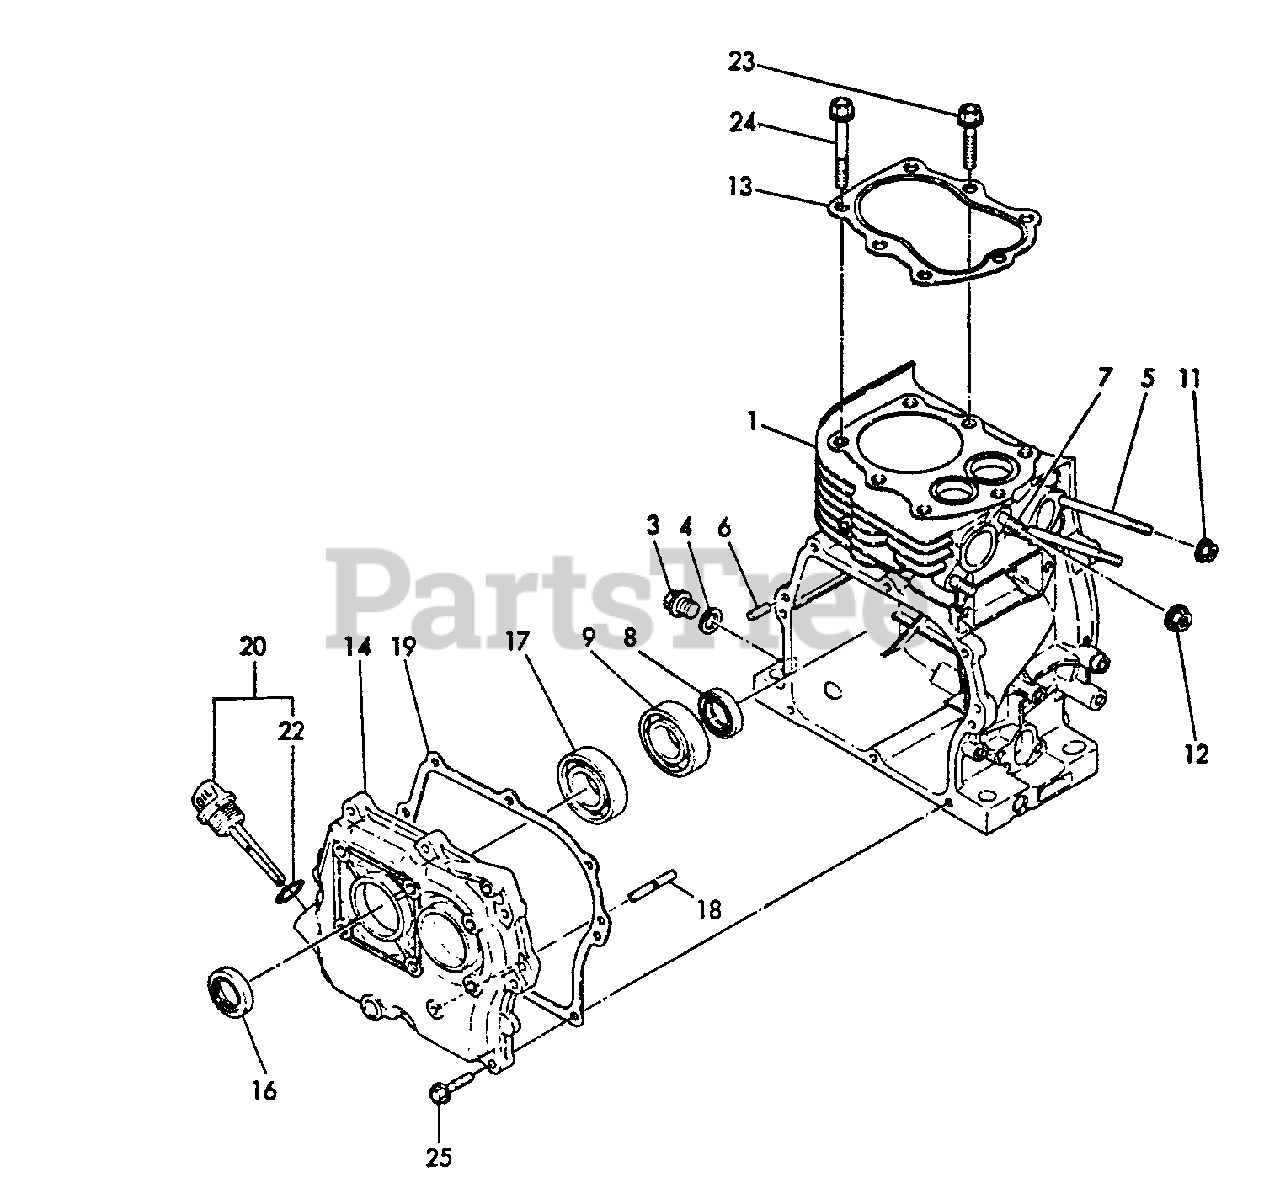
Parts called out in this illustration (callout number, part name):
1	CYLINDER BLOCK SET
3	PLUG, DRAIN
4	GASKET
5	BOLT - 6×70
6	PARALLEL PIN 6×16
7	STUD - 8×18 -- PLATED
8	SEAL, OIL
9	BEARING, BALL
11	U-NUT M6
12	U-NUT M8
13	GASKET, CYLINDER
14	SIDE COVER ASSY
16	SEAL, OIL
17	BEARING, BALL
18	SHAFT, GOVERNOR
19	GASKET, SIDE COVER
20	CAP ASSY
22	O-RING 1A P-18.0
23	BOLT - 8×39
24	BOLT - 8×65
25	BOLT - 6×30
